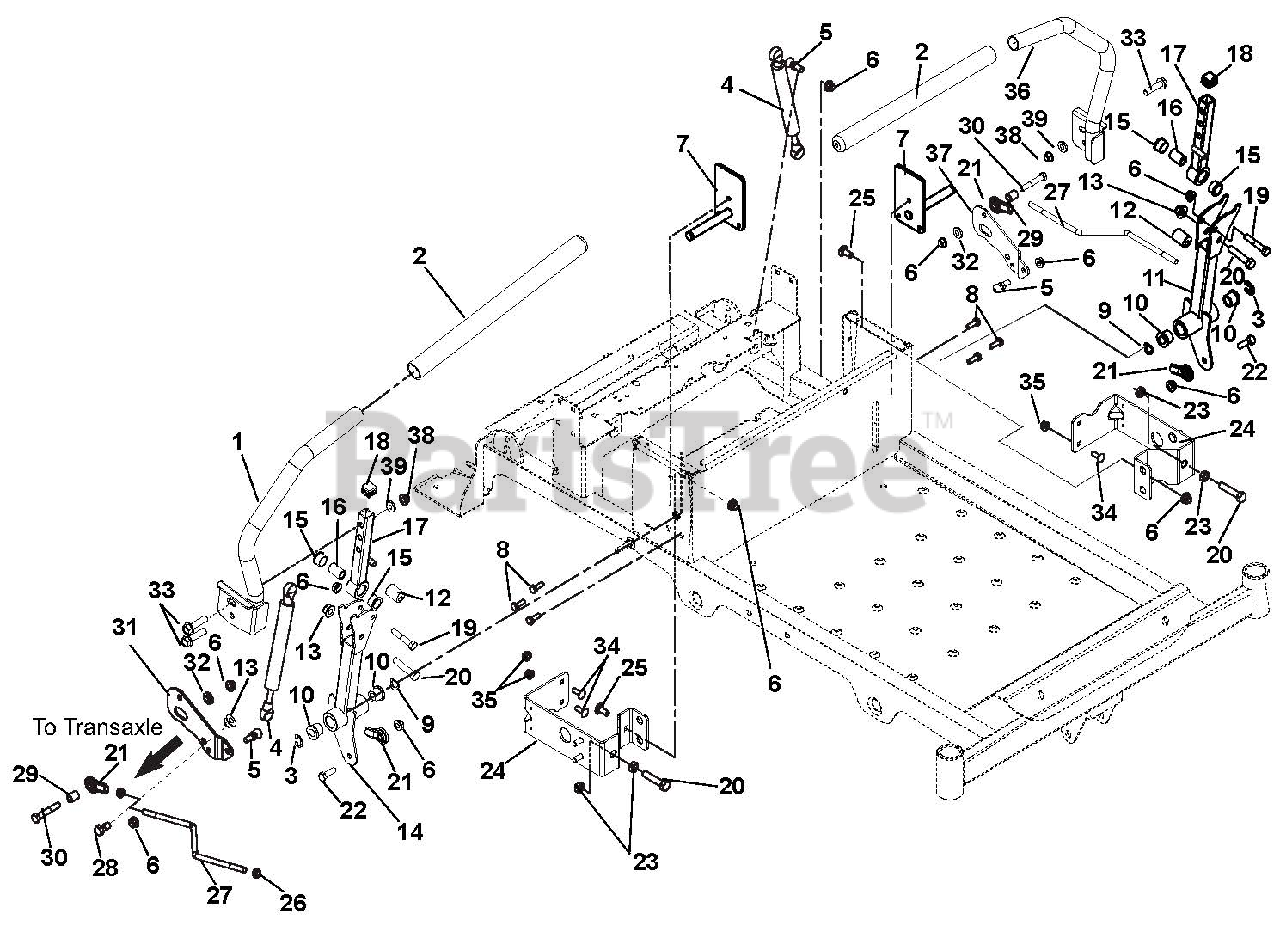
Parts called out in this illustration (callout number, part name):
1	Weldment, Steering Handle Right Hand
2	Grip, Handlebar 15" Foam
3	Ring, Retaining External .438 x 1.00 x 0.83
5	Stud, Ball
6	Nut, .31-18 Flange
7	Weldment, Steering Shaft
8	Screw, Tapping .25-20 x .50 Hex Washer Head
9	Washer, Wave
10	Bushing, Flanged
11	Weldment, Lower Control Arm
12	Bushing, Eccentric
13	Nut, .38-16 Nyloc Flange
14	Weldment, Lower Control Right Hand
15	Bushing, Flanged
16	Spacer, .375 x .625 x .970
17	Weldment, Upper Control Arm
18	Cap Plug, Square
19	Bolt, Hex .31-18 x 1.75
20	Bolt, Hex .375-16 x 1.75
21	Alignaball, 5/16 RH Thread
22	Bolt, Hex .31-18 x 1.00
23	Nut, Hex Jam .375-16
24	Bracket, Speed Adjustment/Seat Pivot
25	Bolt, Round Head Square Neck .31-18 x .75
26	Nut, Jam, .31-24
27	Wireform, Steering Link
28	Bolt, Hex .38-16 x .75
29	Spacer, .328 x .500 x .625
30	Bolt, Hex .31-18 x 2.00
31	Plate, Dampener Right Hand
32	Bushing, Flanged
33	Bolt, Serrated Hex Flange Washer Head .375-16 x 1.25
34	Bolt, Round Head Square Neck .25-20 x .75
35	Nut, Locking Nylon Flange .25-20
36	Weldment, Steering Handle Left Hand
37	Plate, Damper Left Hand
38	Nut, Locking Center Jam .375-16
39	Washer, Flat Steel .406 x .812 x .065
